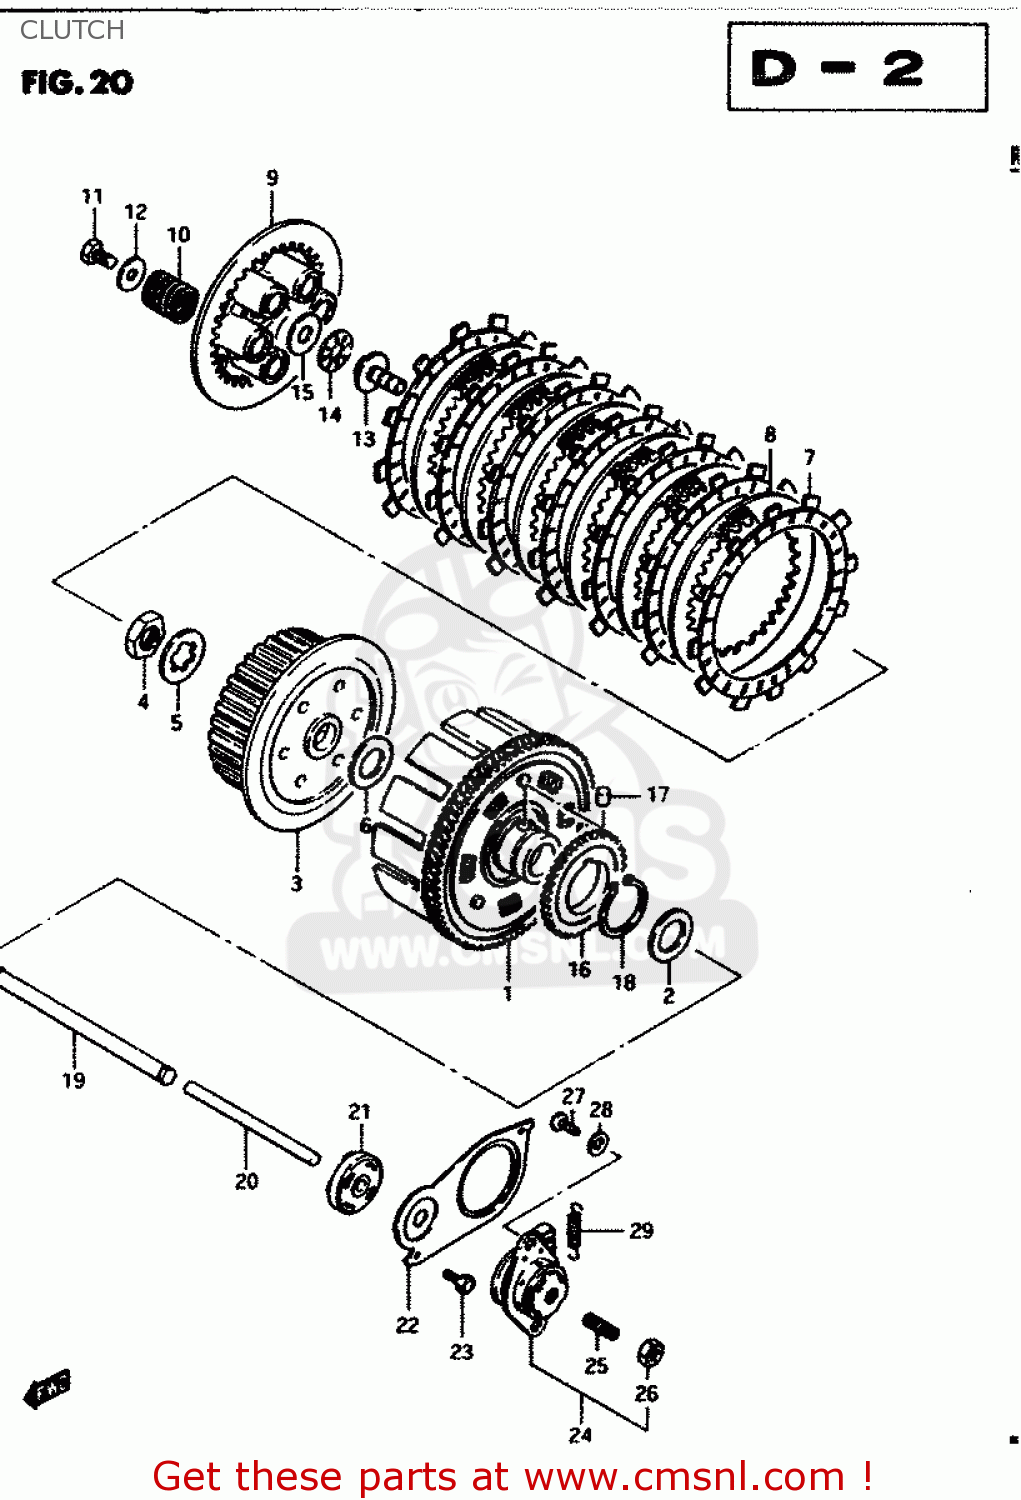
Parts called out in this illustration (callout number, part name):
1	GEAR ASSEMBLY,PRIMARY DRIVE
2	WASHER
3	HUB,CLUTCH SLEEVE
4	NUT (20MM)
5	WASHER,LOCK
6	WASHER(20X44X3)
7	PLATE,CLUTCH DRIVE (MCA)
8	PLATE,CLUTCH DRIVEN (NAS)
9	DISC,CLUTCH PRESSURE
10	SPRING
11	BOLT, UPPER
12	WASHER
13	PIECE,CLUTCH PUSH
14	BEARING(15X28X2)
15	WASHER
16	GEAR,OIL PUMP DRIVE
17	PIN(6X6)
18	CIRCLIP
19	ROD,CLUTCH PUSH
20	ROD,CLUTCH PUSH
21	SEAL,OIL(6X34X10)
22	PLATE,CLUTCH PUSH ROD
23	BOLT
24	SCREW ASSY,CLUTCH RELEASE
25	SCREW
26	NUT 6MM
27	SCREW
28	WASHER
29	SPRING
